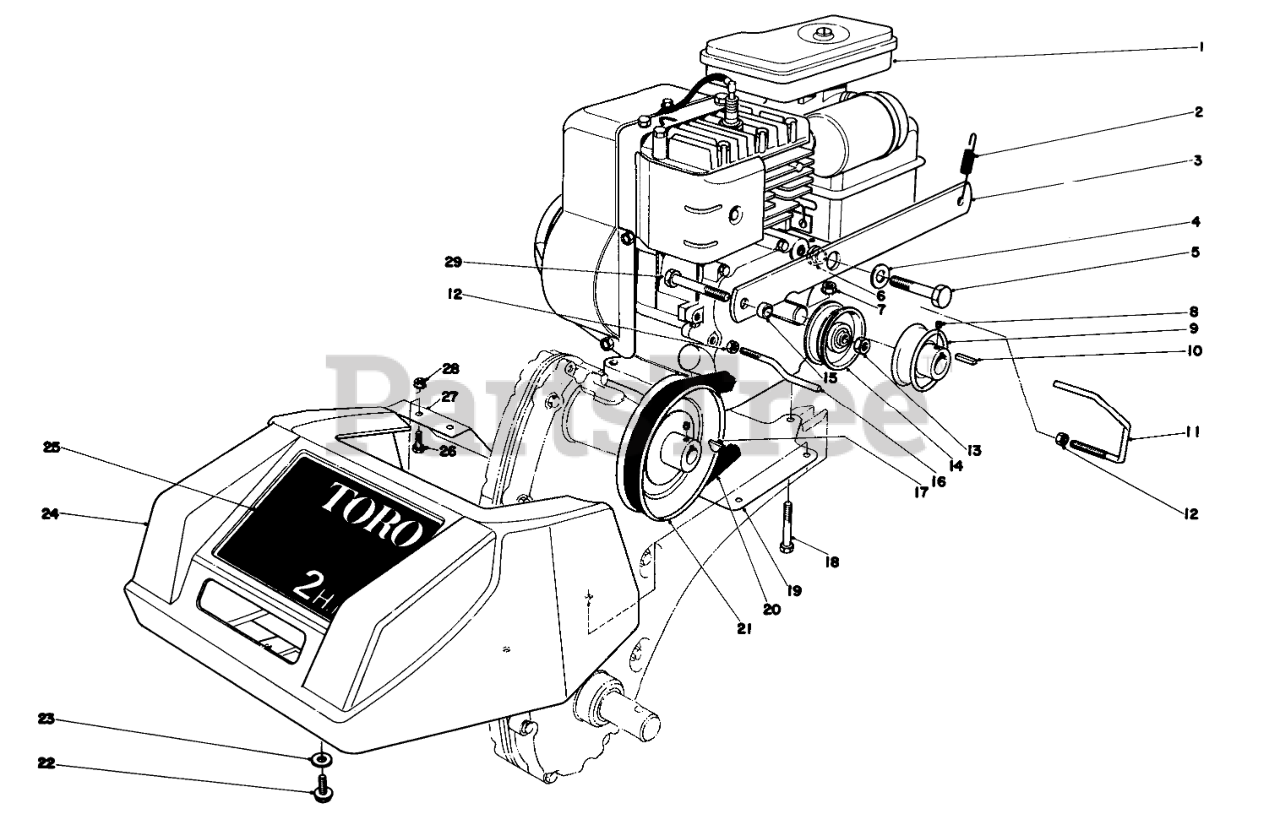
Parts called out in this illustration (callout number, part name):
1	Engine (Model 58307)
2	TENSION SPRING
3	Idler Arm
4	WASHER-FLAT
5	SCREW-HH
6	Spacer Idler Arm
7	NUT-KEPS
8	SCREW-HSH
9	Driver Pulley (Model 58307)
10	KEY-SQUARE
11	Belt Guide
12	NUT-HEX
13	NUT-LOCK, CONE
14	PULLEY-IDLER
15	Spacer
16	Belt Guide
17	KEY-WOODRUFF
18	SCREW-HH
19	Mounting Plate Shield
20	V-Belt
21	Driver Pulley
22	Screw
23	WASHER-PLAIN
24	Shroud
25	Decal (Model 58307)
26	SCREW-HH
27	Shield
28	NUT-HEX, SIDE DEFORM
29	SCREW-HH
